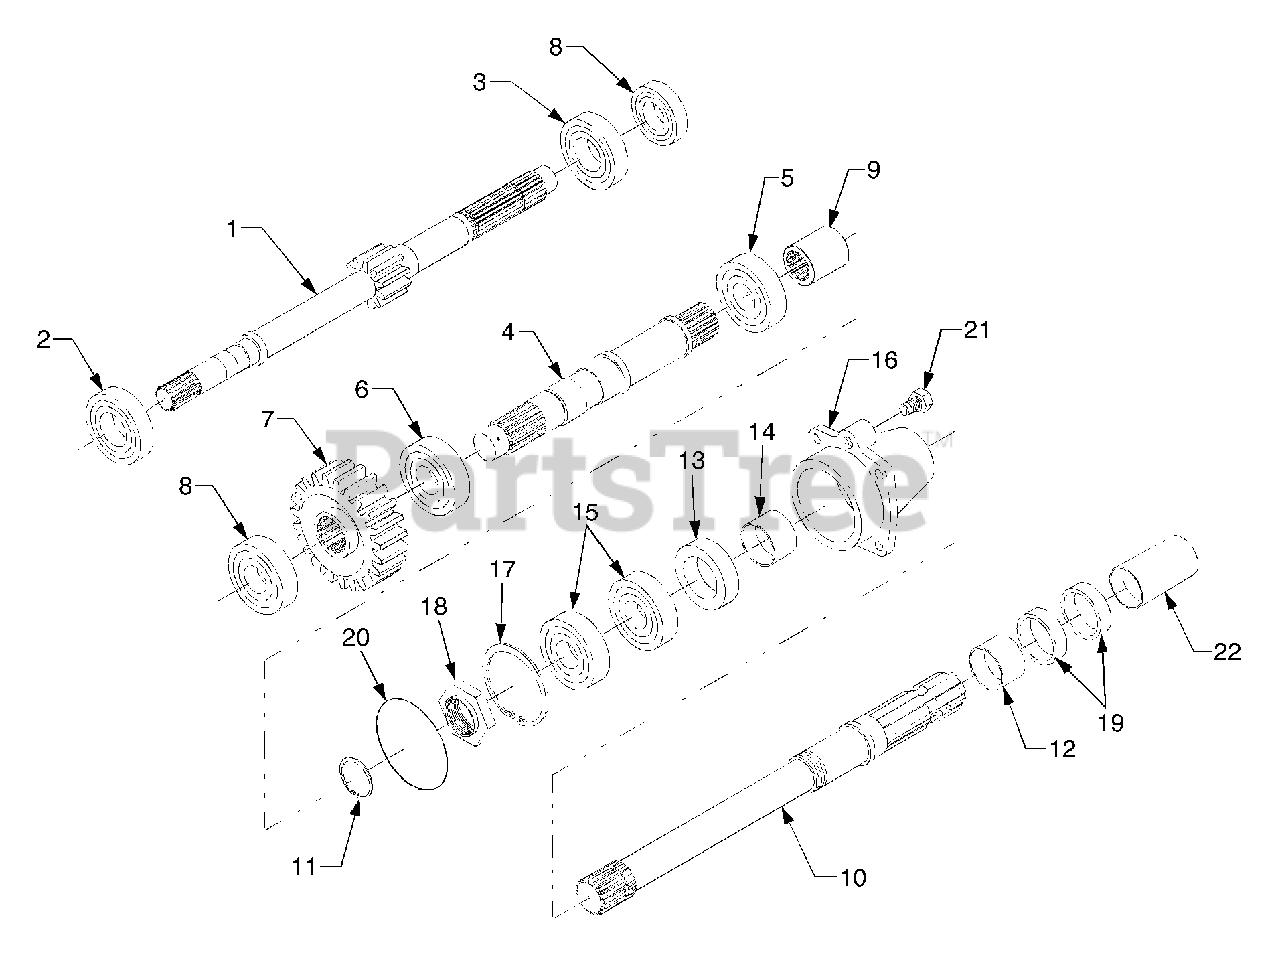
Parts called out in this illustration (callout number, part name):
1	Shaft, 12 Gear
2	Bearing, Ball
3	Bearing, Ball
4	Shaft, PTO Drive
5	Bearing, Ball
6	Bearing, Ball
8	Bearing, Ball
13	Seal, Oil
14	Collar, Oil Seal
15	Bearing, Ball
16	Case, Bearing
22	Cover, PTO Shaft
